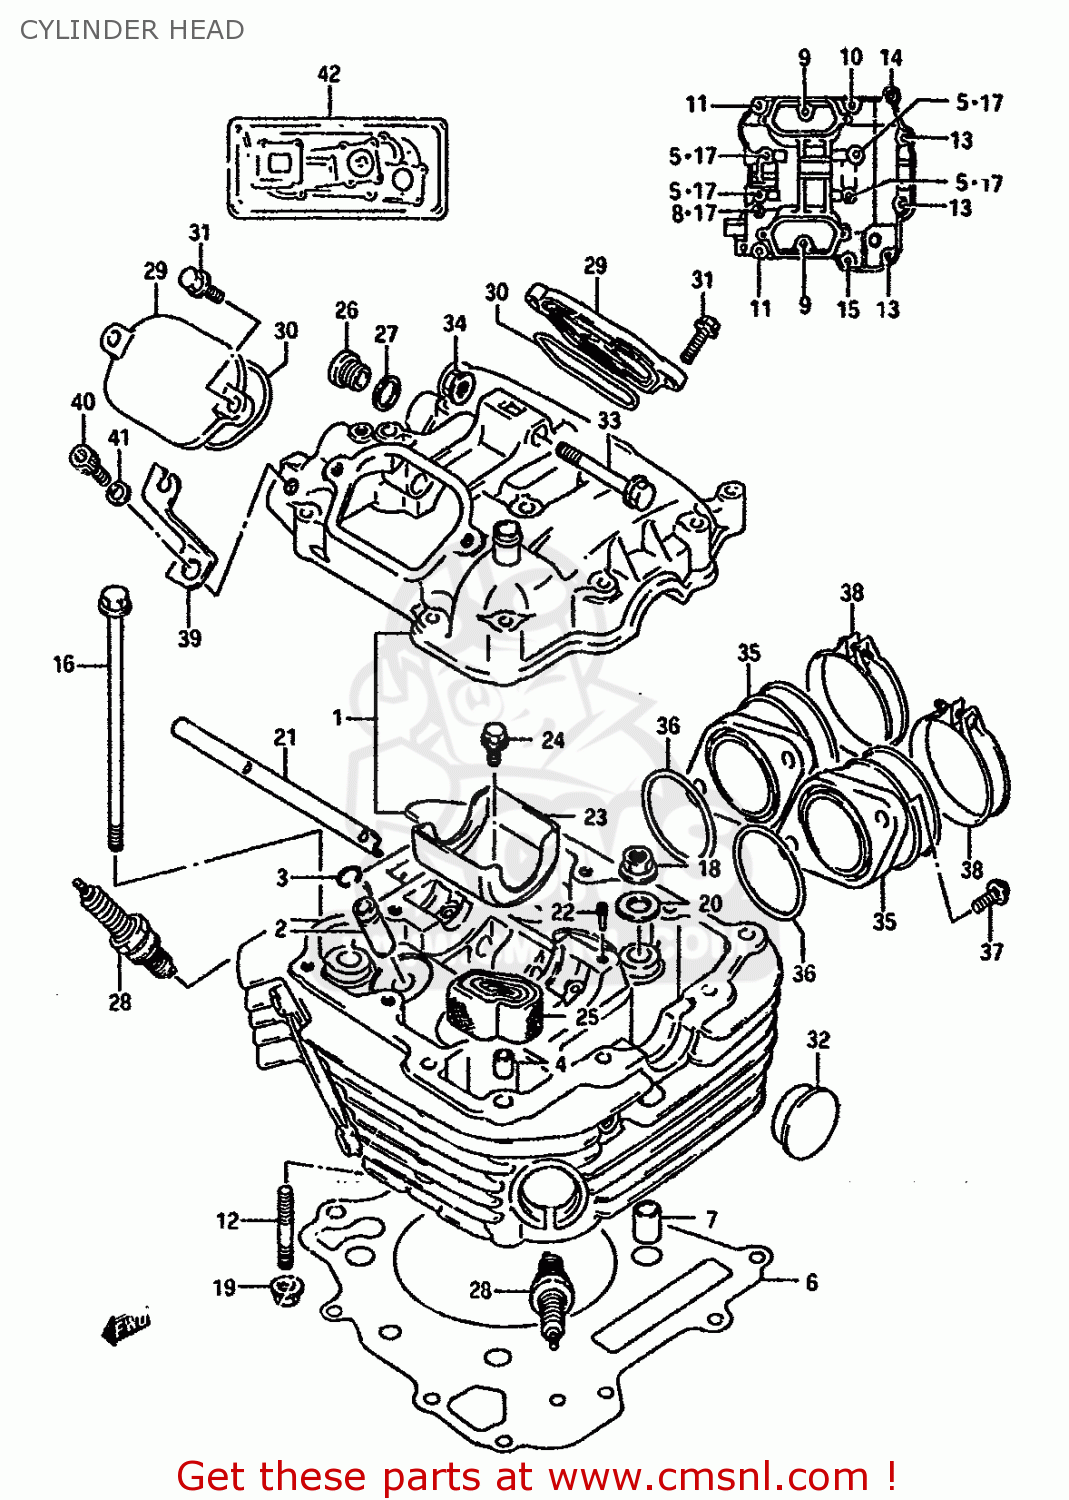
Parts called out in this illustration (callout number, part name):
1	HEAD ASSY,CYLINDER (BLUE)
2	GUIDE,VALVE
3	RING,SNAP
4	PIN(6.2X8X11)
5	BOLT(6X55)
6	GASKET,CYLINDER HEAD (NAS)
7	PIN
8	BOLT 6X16
9	BOLT
10	BOLT
11	BOLT 6X35
12	BOLT,STUD(8X31)
13	BOLT(6X125)
14	BOLT(6X115)
15	BOLT(6X105)
16	BOLT(8X155)
17	GASKET(5.8X13X1.2) (NAS)
18	NUT
19	NUT 8MM
20	WASHER(10.5X22X2.3)
21	PIPE,OIL
22	SCREW (L:19.5)
23	PLATE, OIL CHAMBER
24	BOLT
25	SEPARATOR,OIL
26	PLUG,14X12
27	GASKET(14X19.2X2) (NAS)
28	SPARK PLUG DP9EA-9
29	CAP,INSPECTION
30	O-RING,INSPECTION CAP
31	BOLT 6X20
32	PLUG(OD:30)
33	BOLT 8X50
34	NUT
35	PIPECOMP,INT
36	O RING(D:2.4,ID:39.7)
37	SCREW
38	CLAMP
39	HOLDER,DECOMP CABLE
40	BOLT
41	WASHER
42	GASKET SET
